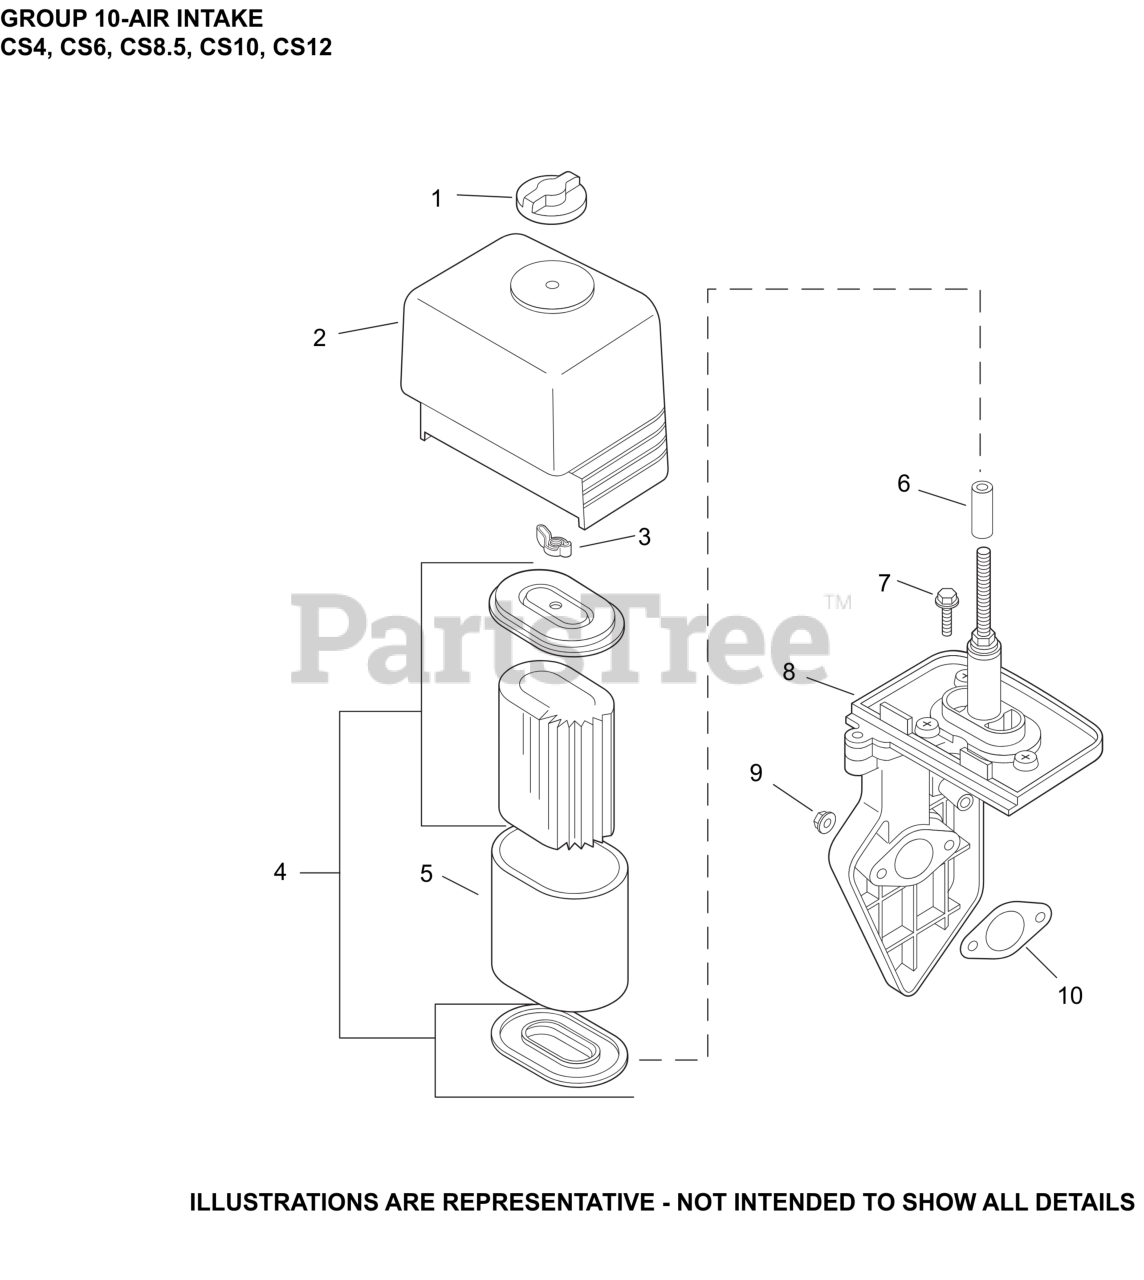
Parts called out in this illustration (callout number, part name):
1	NUT-(#DSC)
2	COVER,A/C
3	NUT, WING A/C
5	PRECLEANER, ELEMENT
8	BASE, A/C
10	GASKET A/C
